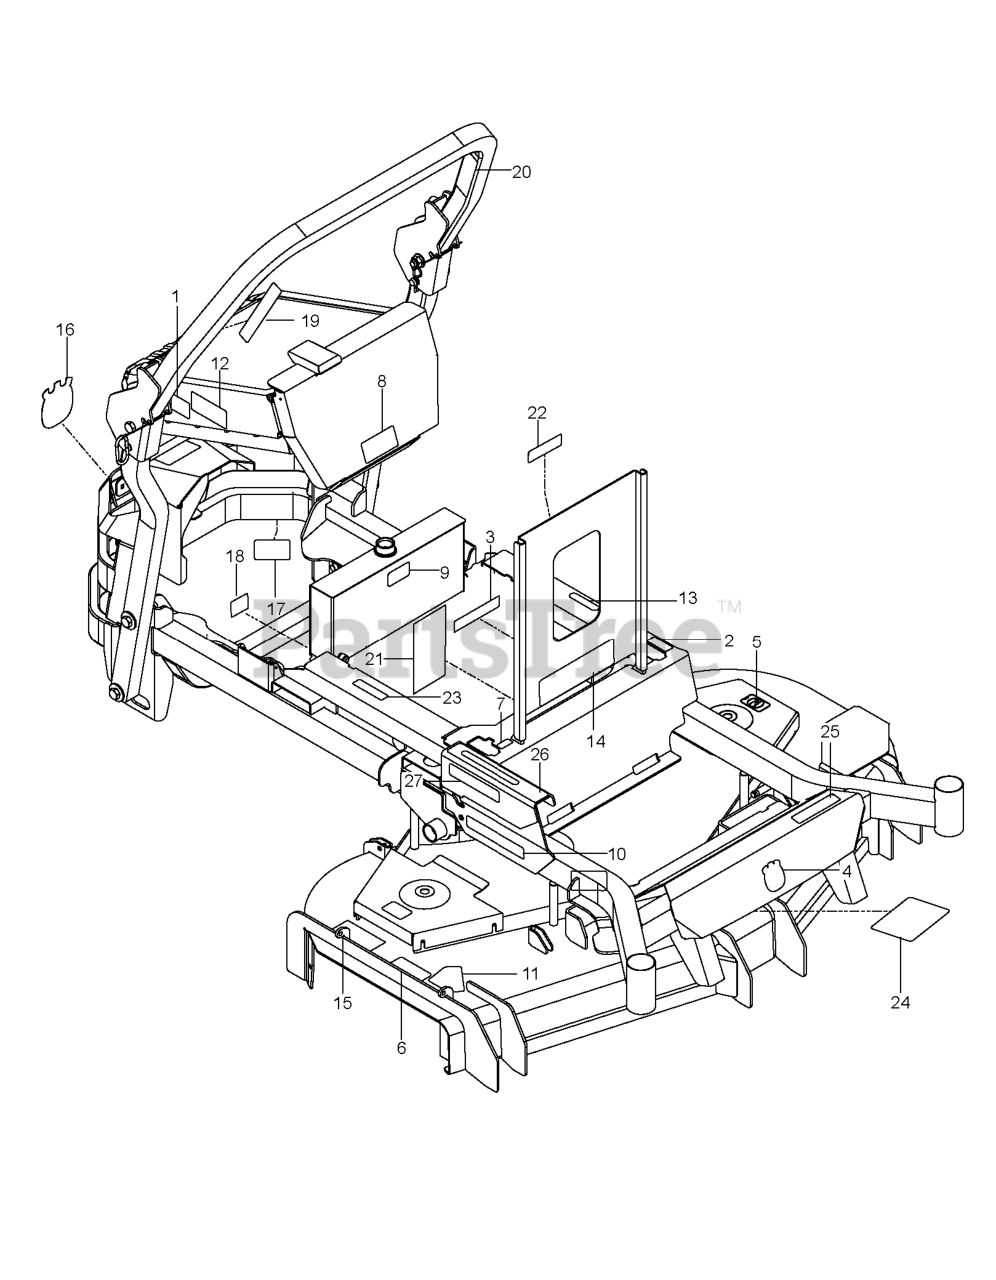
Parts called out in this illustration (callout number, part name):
1	DECAL, DEBRIS SCREEN
2	DECAL, MOTION CONTROL
3	EURO DECAL-BATTERY WARNIN6
4	DECAL.AUGER.HUSQ.CROWN.SNOW
5	DECAL, NO STEP
6	DECAL, CAUTION
7	DECAL, F.S.T.
8	DECAL, BELT DRIVE
9	DECAL, OIL TANK
10	RP.DECAL.BADGE.170MM.TEXTLOGO
11	DECAL, CPSC
12	DECAL, HOT
13	DECAL, PARK BRAKE
14	DECAL, WARNING
15	DECAL, EURO SEVERING
16	DECAL, CROWN H, 110MM
17	DECAL, PROP. 65
18	DECAL, HYDRO BELT
19	DECAL, ROPS, WARNING
20	DECAL, ROPS, DIESEL
21	DECAL, SERVICE, DIESEL
22	DECAL, FUSE, DIESEL
23	DECAL, WARNING SPARK ARRESTOR
24	DECAL, BELT ROUTING
25	DECAL, PZ29D
26	DECAL, HEIGHT CE
27	DECAL, HEIGHT CE
